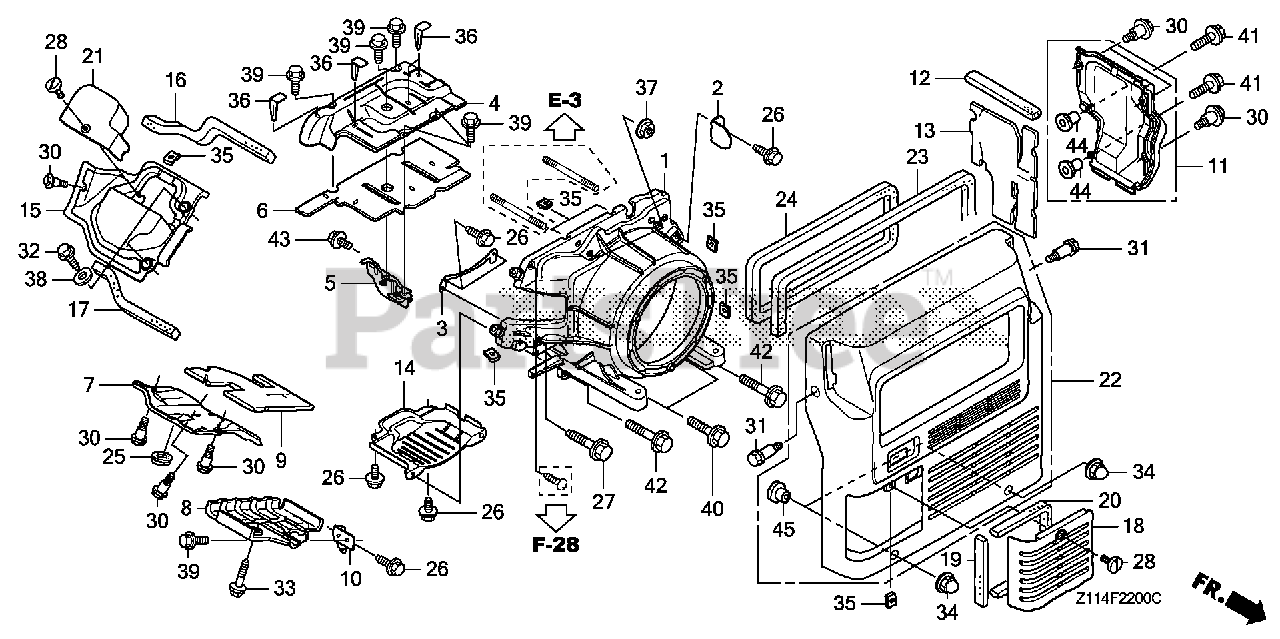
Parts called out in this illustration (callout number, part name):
1	COVER, FAN
2	PLATE, R. SIDE
3	BRACKET, FAN COVER
4	SHROUD (UPPER)
5	BRACKET, SHROUD (UPPER)
6	INSULATOR, SHROUD (UPPER)
7	SHROUD (LOWER)
8	SHROUD, ENGINE
9	INSULATOR, SHROUD (LOWER)
10	BRACKET, SHROUD (LOWER)
11	SHROUD, R. SIDE
12	SEAL, R. SIDE COVER
13	INSULATOR, R. SIDE COVER
14	SHROUD (LOWER)
15	SHROUD, HEAD COVER
16	SEAL, HEAD COVER SHROUD (UPPER)
17	SEAL, HEAD COVER SHROUD (LOWER)
18	COVER, MAINTENANCE *NH314* (CONDUCT GRAY)
19	SEAL A, MAINTENANCE COVER
20	SEAL B, MAINTENANCE COVER
21	COVER, PLUG
22	COVER, FR. *NH314* (CONDUCT GRAY)
23	SEAL A, FR. COVER
24	SEAL C, FR. COVER
25	GROMMET, SPEAKER PANEL
26	BOLT, FLANGE (6X12) (CT200)
27	BOLT, FLANGE (6X23)
28	BOLT, AIR CLEANER COVER (- SCREW)
28	SCREW, SPECIAL (6X16)
30	BOLT, SPECIAL (6MM)
31	BOLT, SPECIAL (6X26)
32	BOLT, FLANGE (6X12) (CT200)
33	BOLT, FLANGE (6X25) Use up to Engine SN 2056819.
34	NUT, OPEN STAY (6MM)
35	NUT, SPRING (6MM)
36	CLIP, INSULATOR BIND (A)
37	NUT, FLANGE (6MM)
38	WASHER, PLAIN (6MM)
39	BOLT, FLANGE (6X12) Use up to Engine SN 1543277.
40	BOLT, FLANGE (6X20)
41	BOLT, FLANGE (6X22)
42	BOLT, FLANGE (6X30)
43	BOLT, FLANGE (6X12) Use up to Engine SN 1543277.
44	COLLAR, FAN COVER (Honda Code 5580527). (N/A: SEE ASSEMBLY)
45	COLLAR, FR. COVER
